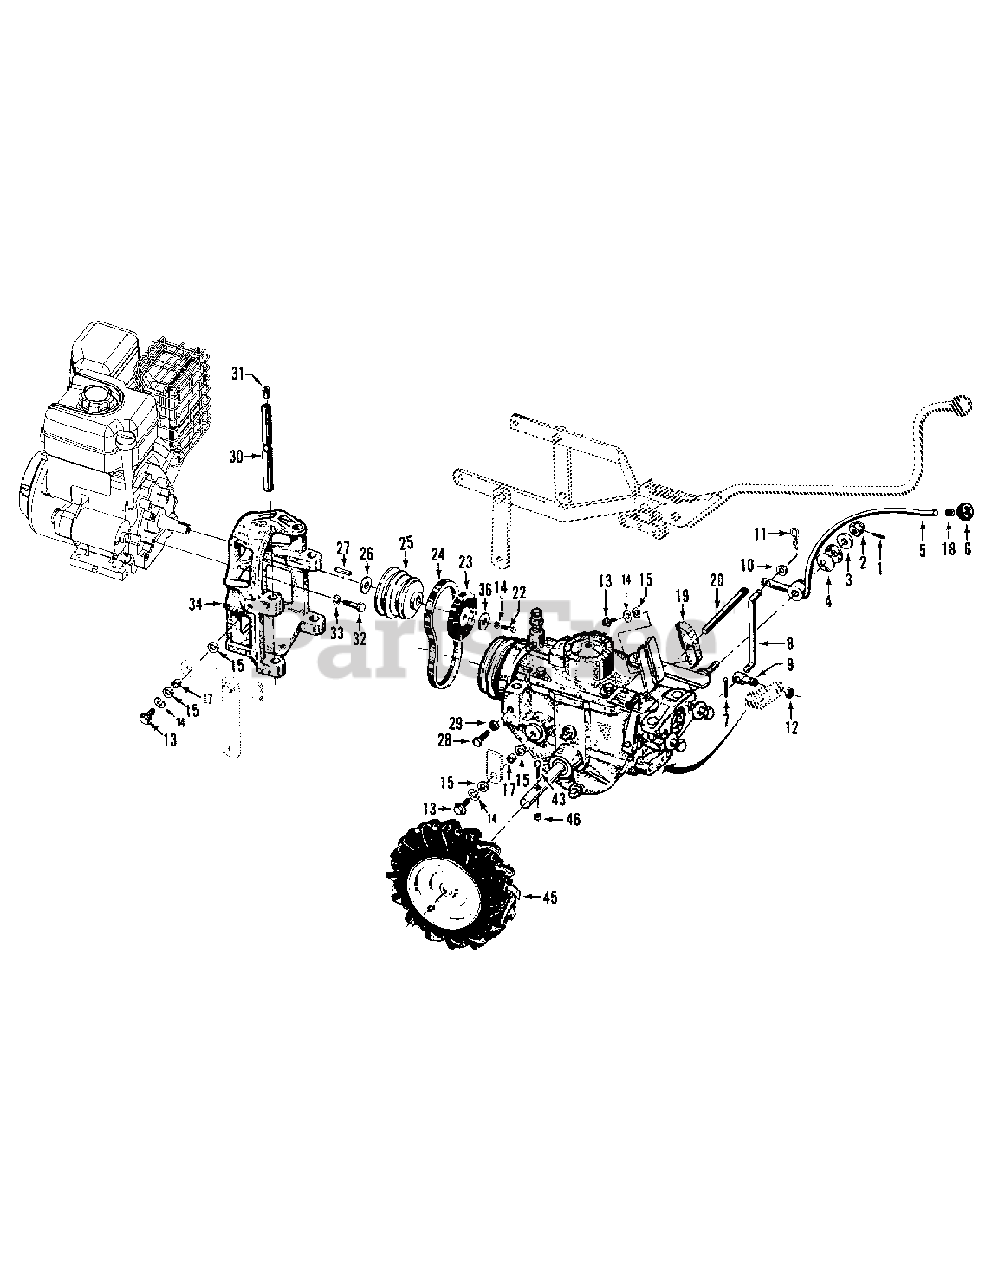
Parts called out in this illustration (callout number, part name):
1	Pin-spring, 1/8"
2	Nut-castle (slotted), 1/2"-20
3	Washer-shoulder, 1/2"
4	Washer-disc spring
5	Lever-wheel speed shift
6	Knob-wheel speed shift lever
7	Pin-cotter, 3/32" x 1"
8	Connecting rod, wheel speed lever -shift (Incl. Ref. 7 & Ref 9)
9	Swivel-connecting rod
10	Washer-flat, 5/16", SAE
11	Pin-hair cotter
12	Locknut-hex hd., 5/16"-18
13	Bolt-flanged hex hd., 3/8-16 x 1"
14	Lockwasher-spring lock, 3/8"
15	Washer-flat, 3/8", SAE
17	Bushing-spacer, 19/64" (300"lg.)
18	Ring-retaining (tolerance ring)
19	Block Kit - belt adjustment, 3/8-24 x 1-1/2"
20	Rod- belt adjust., 7" with measuring gauge
21	Decal- engine stabilization
22	Bolt-hex hd., 3/8-24 x 1-1/2"
23	Disc-reverse
24	Belt-forward drive
25	Pulley-engine power take off
26	Shim-engine pulley, 1/16"
26	Shim-as above, 1/32"
27	Key-engine Pulley 3/16"sq. 2-1/2"
28	Bolt-hex hd 5/16-18 x 1:, Grade 5
29	Nut, 5/16-18 hex, 5/16-18
30	Bar-engine mounting
31	Plug-thread protector, red plastic
32	Bolt-hex hd., 5/16-24 x 1-1/8"
33	Lockwasher-spring lock, 5/16
34	Mount-engine to tiller
36	Washer, flat, .406 x 1.0 x .105
43	Screw, Hex 1/4-20 x 1 1/2"
45	Wheel & Tire Assembly 16 x 4:6 x 8" tubeless tire with valve stem, on one-piece steel rim
46	Nut, Hex Flange 1/4-20
